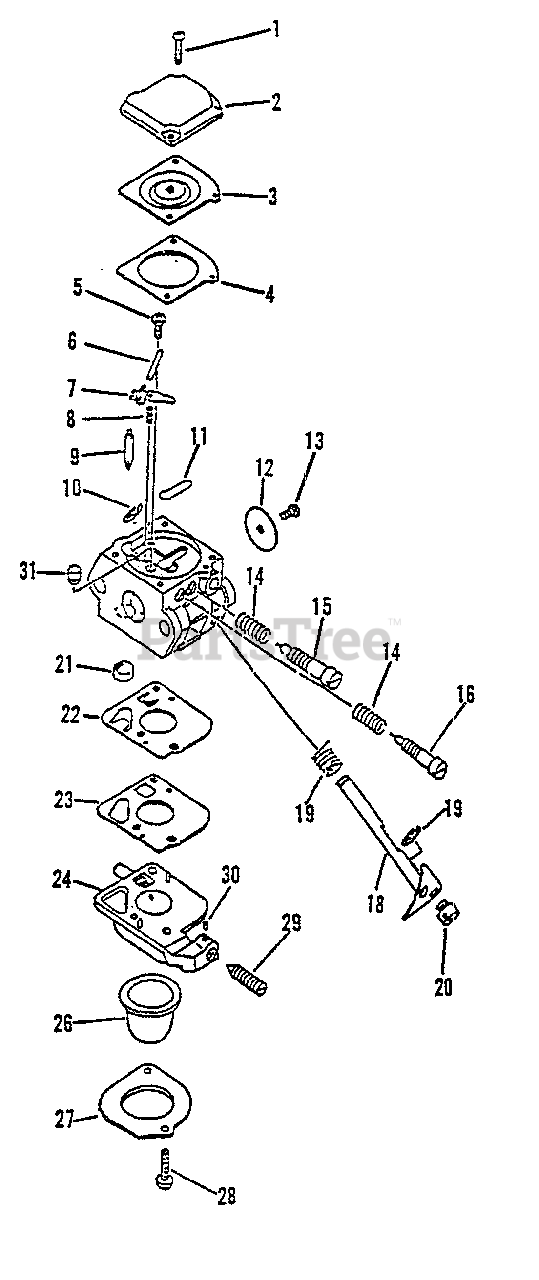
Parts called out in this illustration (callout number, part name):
2	COVER, DIAPHRAGM
3	DIAPHRAGM
4	GASKET, METERING
6	PIN
7	LEVER, METERING
8	SPRING
9	VALVE, NEEDLE
11	PLUG, WELCH
12	VALVE, THROTTLE
14	SPRING, NEEDLE
15	NEEDLE, HIGH SPEED
16	NEEDLE, IDLE
17	SPRING, THROTTLE RETURN
18	SHAFT, THROTTLE
21	STRAINER
24	BODY ASSY, PURGE
26	BULB, PURGE
27	RETAINER
29	SCREW, IDLE ADJUST
30	PIECE, FRICTION
31	NOZZLE, CHECK VALVE
